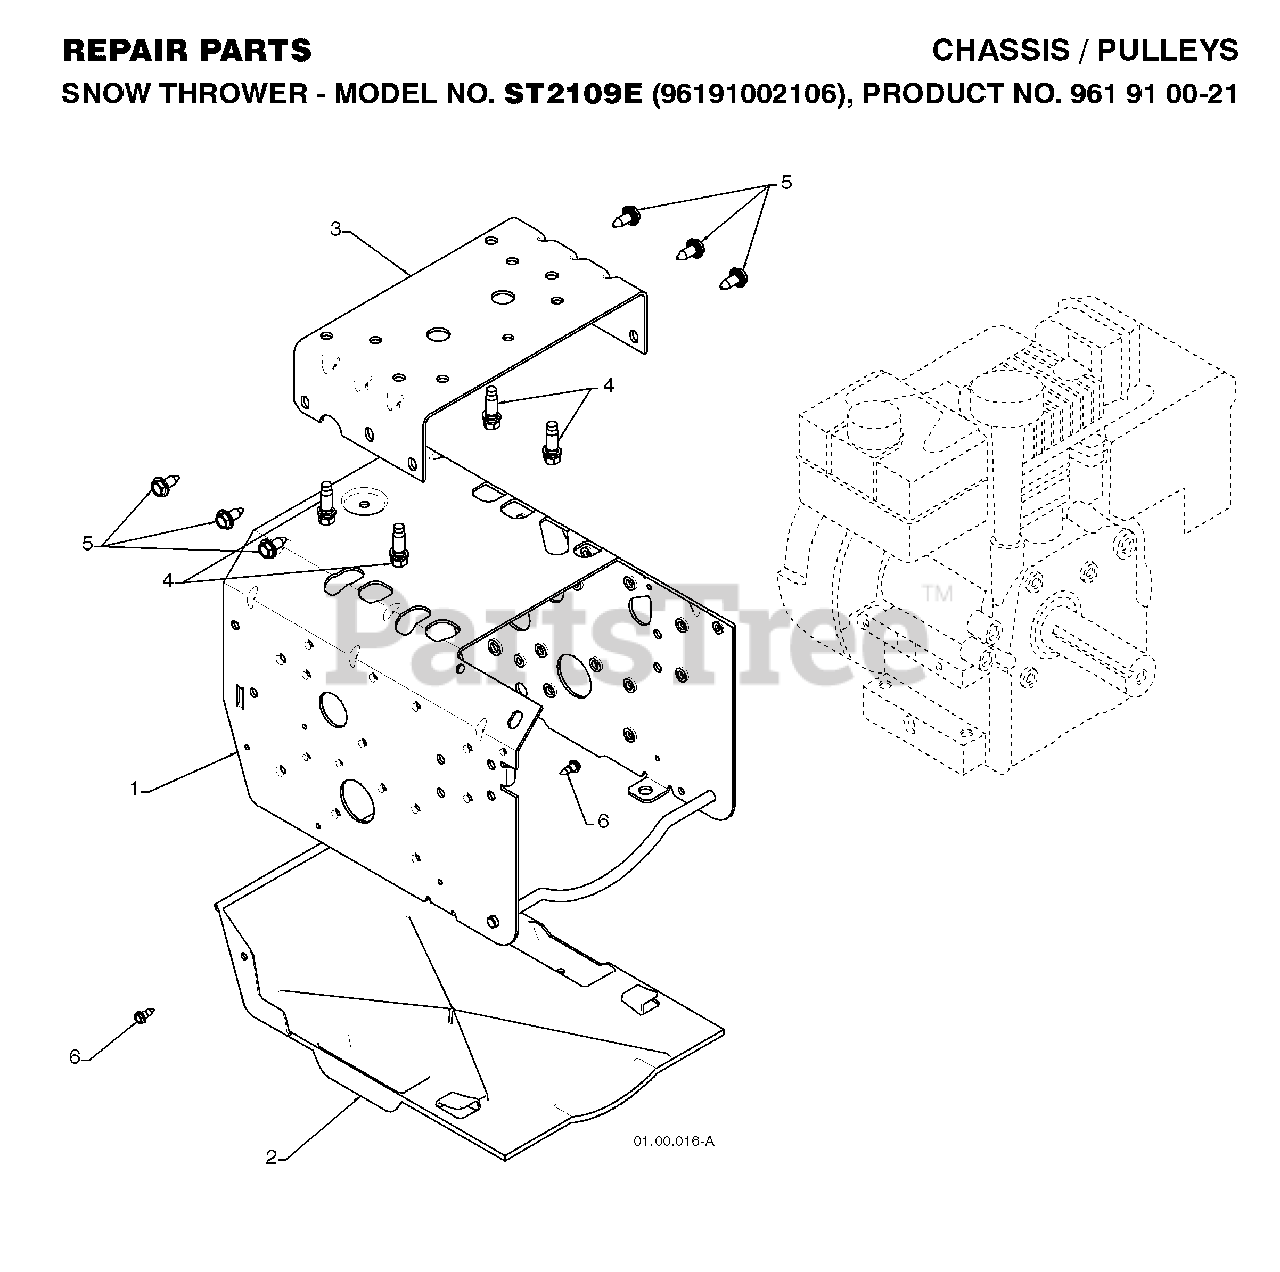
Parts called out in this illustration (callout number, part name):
2	PAN.BOTTOM.PLASTIC
4	BOLT 3/8-16X1-1/8
5	SELF-TAPPING SCREW 5/16-18X3/4
6	SCREW, HEX HEAD, TAPPING
